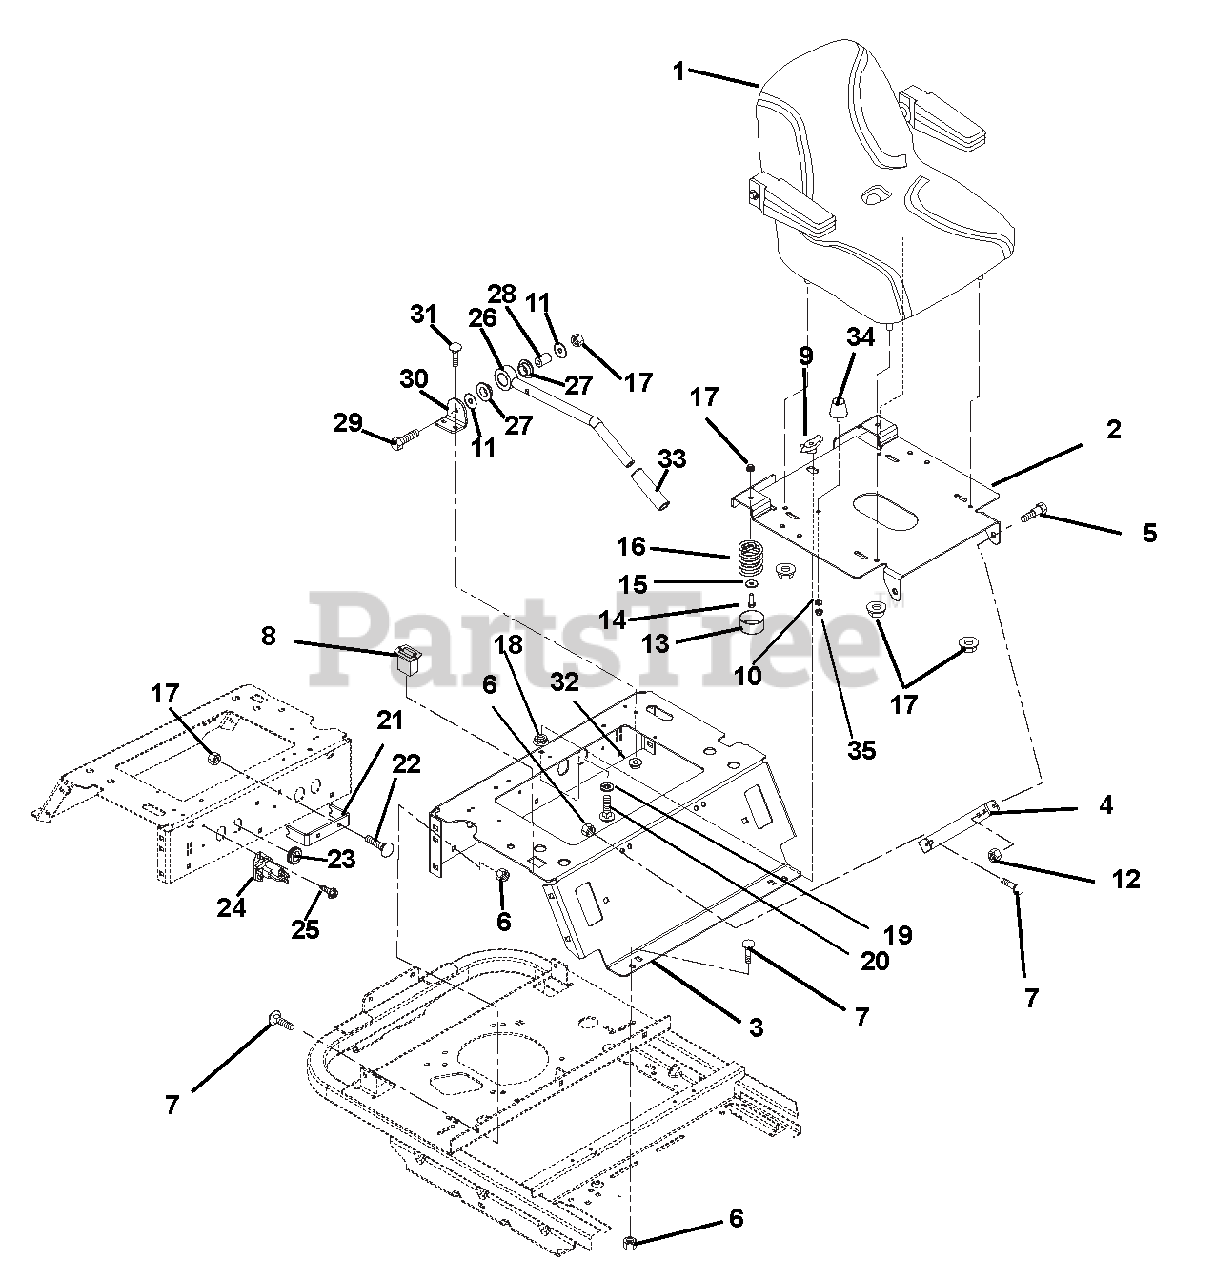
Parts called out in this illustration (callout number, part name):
1	ASSM, SEAT W/REPLA ARMRESTS
1	KIT, COMPLETE ARMREST
2	BRACKET, SEAT PLATE
3	SEAT SUPPORT
4	BRACKET, SEAT PLATE
5	BOLT-SHLDR .375-16X.150
6	@NUT-LK-NYL-FLG .38-16 YWZC
7	@BLT-RDHDSQNK .38-16X1.00 G5YZ
8	HOUR METER - DIGITAL
9	KNOB - WING .312-18 UNC
10	@WSHR-LK .31X.078 REG YWZC
11	WSHR-FL-STL .347X1.254X.048YWZ
12	@NUT-LK-TOP-FLG .38-16 YWZC
13	HUB CAP
14	@BLT-HEX .31-18X1.00 GR5 YWZC
15	WSHR-FL-STL .328X1.0X.094 YWZC
16	SPRING, SEAT
17	@NUT-LK-NYL-FLG .31-18 YWZC
18	@NUT-SPNLK-FLG .312-18 YWZC
19	WSHR-FL-STL .505X1.00X.062YWZC
20	BLT-RDHDSQSHNK.31-18X2.75G2YWZ
21	BRAKE ROD SUPPORT
22	@BLT-RDHDSQNK .31-18X1.00 G5YZ
23	GROMMET 1.0ID X 1.38 OD
24	SOLENOID
25	@SCR-TAP .25-20X.37 HWH YWZ TR
26	WMT, PARK BRAKE
27	BSHG-FLG .762X1.48X.44 NYL
28	SPACER .328 X .76 X 1.01
29	@BLT-HEX .31-18X1.75 GR5 YWZC
30	BRKT, BRAKE HANDLE PIVOT
31	@BLT-RDHDSQNK .25-20X.75 G5YZ
32	@NUT-LK-TOP-FLG .25-20 YWZC
34	BUMPER, RUBBER CONE,STUD MOUNT
35	@NUT-SPNLK-FLG .312-24 YWZC
